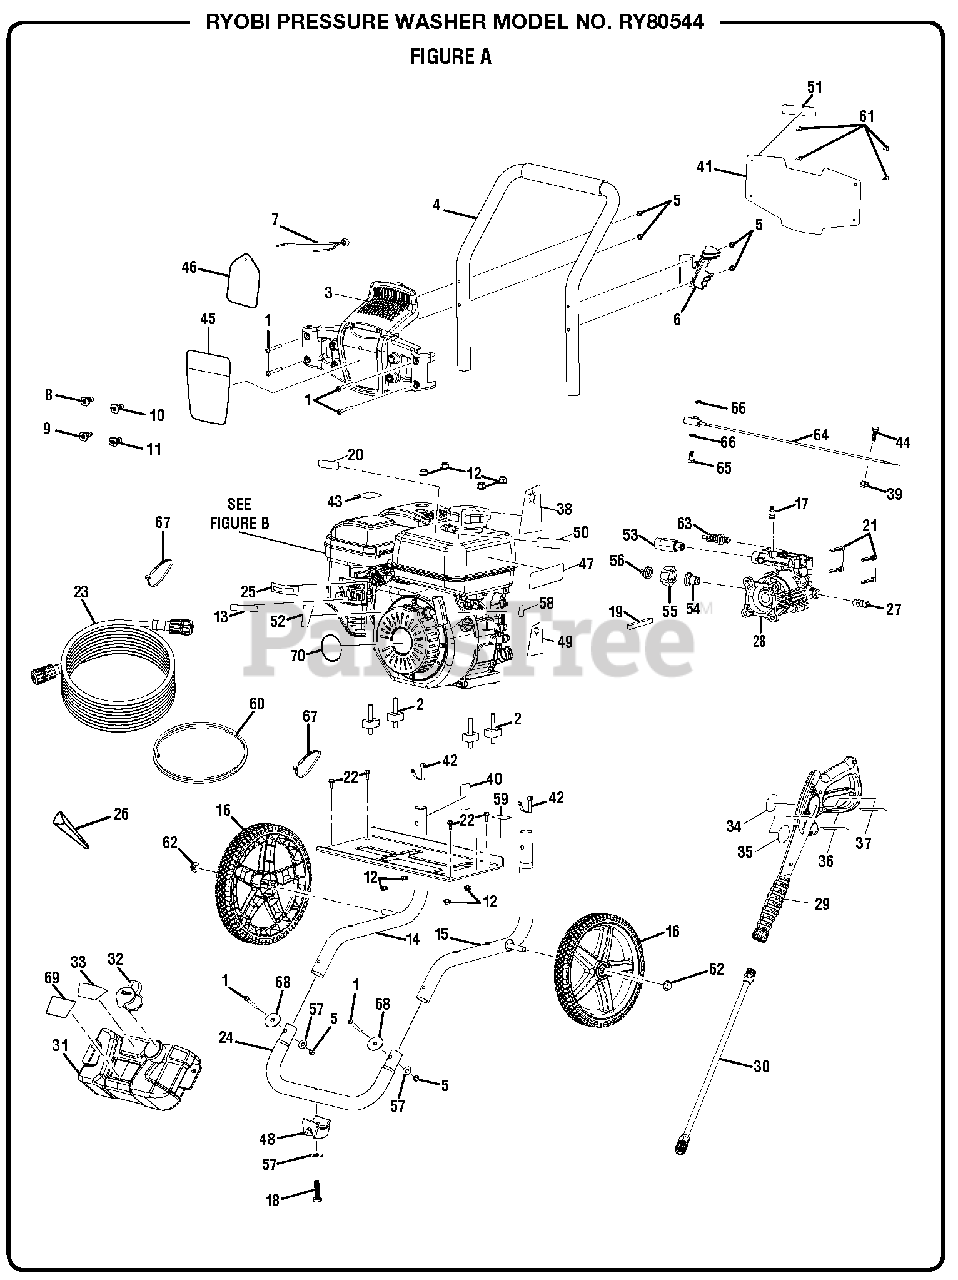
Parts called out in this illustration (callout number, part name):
1	Screw (M6 x 48 mm, T30 Torx Hd.)
2	Engine Isolator
3	Hose and Nozzle Holder Assembly
4	Handle w/Foam
5	Lock Nut (M6)
6	Wand Holder
7	Bungee Cord Assembly
8	40deg Nozzle
9	Soap Nozzle
10	25deg Nozzle
11	0deg Nozzle
12	Flange Nut (M8 x 1.25)
13	Fuel On-Off Label
14	Main Frame Assembly (Left)
15	Main Frame Assembly (Right)
16	Wheel
17	Detergent Suction Kit
18	Bolt (M6 x 25 mm, T30 Torx Hd.)
19	Output Shaft Key (40 mm)
20	Do Not Mix Label
21	Bolt (5/16-24 x 23 mm, Soc.Hex Hd.)
22	Flange Bolt (M6 x 16 mm)
23	Hose (25 ft.)
24	Front Frame
25	Choke Label
27	Thermal Release Valve
29	Trigger Handle Assembly
30	Extension Wand
31	Soap Tank
32	Soap Tank Cap
33	Soap Dilution Label
34	Label (Wand Logo)
35	Warning Label (En)
36	Warning Label (Fr/Sp)
37	Label (Wand Rating)
38	Danger Hangtag
39	Cable Clamp
40	Combustion Warning Label
41	Quick Start Panel
42	Lock Button w/Spring Clip
43	Hot Surface Label
44	Bolt (M5 x 20 mm)
45	Performance Label
46	Nozzle Hangtag
47	Danger Label
48	Rubber Foot
49	Dipstick Hangtag
50	No E85 Label
51	Inquiries Label
52	Fuel Valve Label
53	Outlet Tube
56	Filter Screen (Pump Inlet)
57	Washer (1/4 in.)
58	Engine On/Off Label
59	Oil Fill Location Label
60	Chemical Siphon Tube
61	Screw (#6-20)
62	Push Cap Nut
63	Unloader Valve Assembly
64	Idle Down Throttle Valve Assembly
65	Bolt (M10 x 1.5 mm, Banjo)
66	Bonded Compression Seal
68	Fender Washer (1/4 in.)
69	Soap Tank Label
70	Recoil Label
